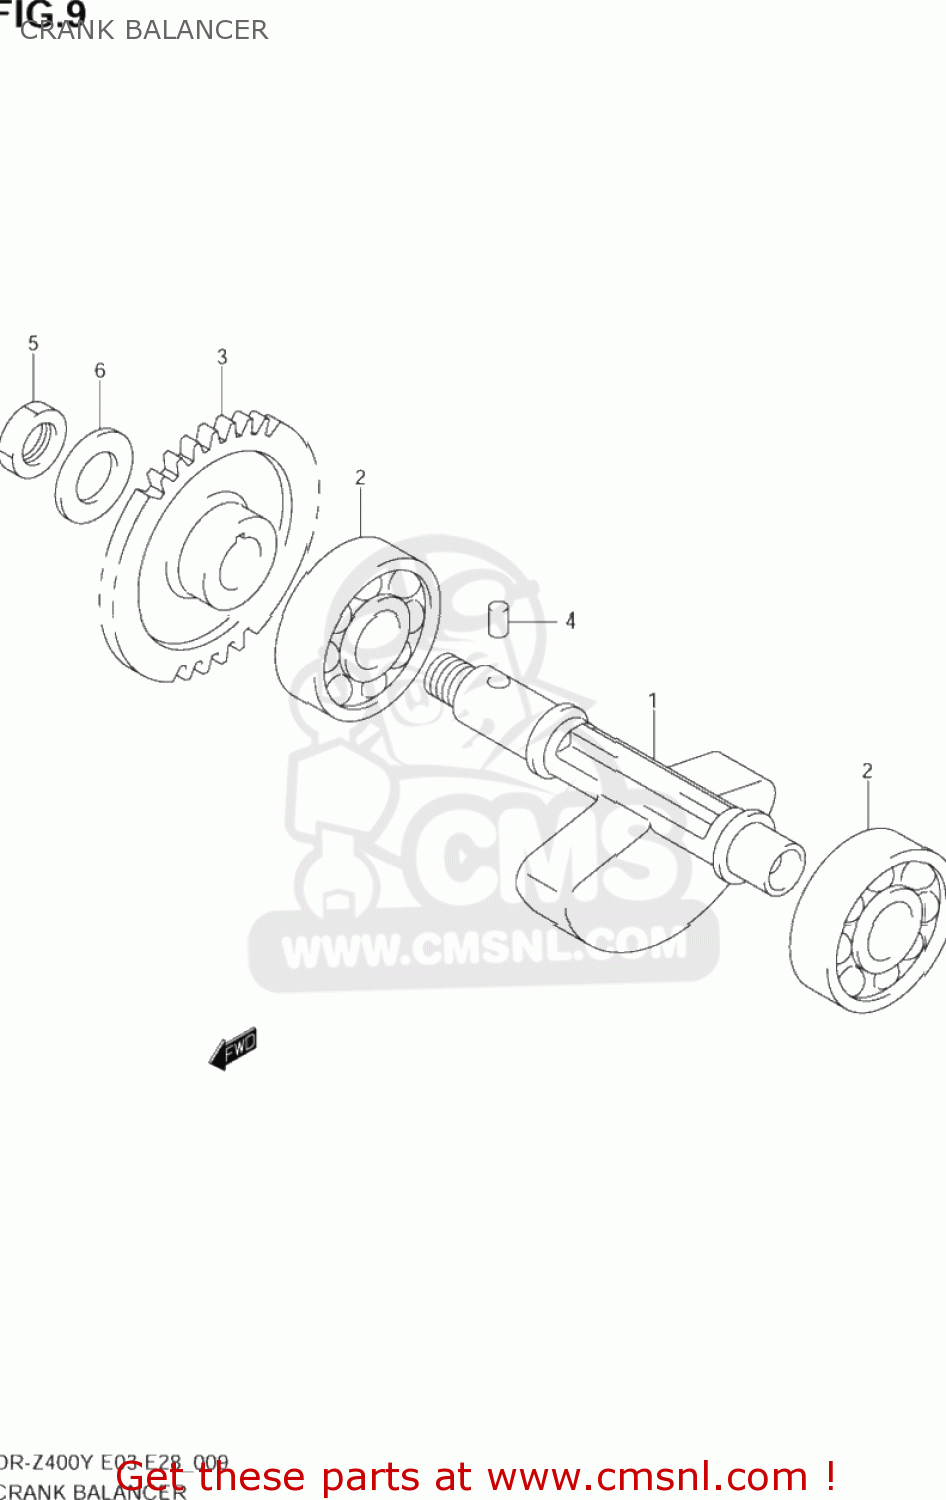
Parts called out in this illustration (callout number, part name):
1	BALANCER,CRANK
2	BEARING(15X42X13)
3	GEAR,CRANK BALANCER DRIVEN
4	PIN(5X8)
5	NUT
6	WASHER(12.5X26X1.6)
